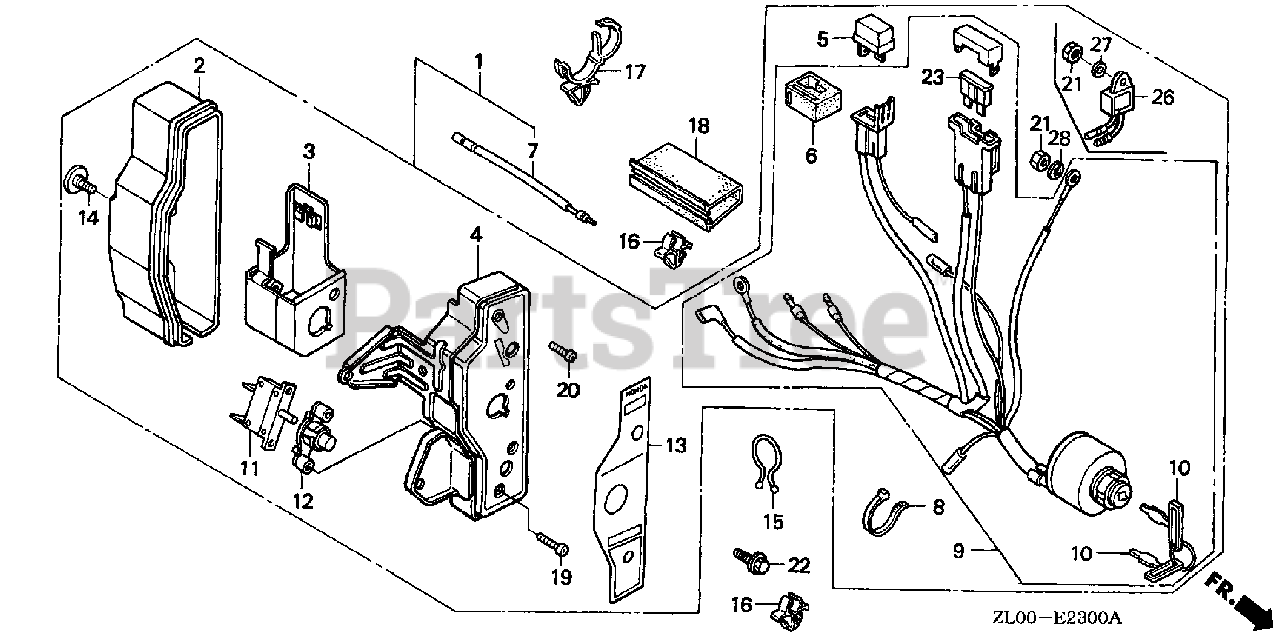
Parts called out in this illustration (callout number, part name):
1	BOX ASSY., CONTROL (EXP,10A) *R8* (BRIGHT RED)
2	CASE, CONTROL
3	BRACKET, CASE MOUNTING
4	PANEL, CONTROL *R8* (BRIGHT RED)
7	SUB-HARNESS
8	BAND
9	SWITCH ASSY., COMBINATION (10A CHG/RCM)
10	KEY
13	MARK, CONTROL BOX (EXTERNAL-REGULATOR)
14	SCREW, SPECIAL (6X12)
18	TUBE, FASTENER (30)
20	SCREW, PAN (4X12)
21	NUT, HEX. (4MM)
22	BOLT, FLANGE (6X10)
23	FUSE, BLADE (15A)
26	ALERT UNIT, OIL
27	WASHER, PLAIN (4MM)
28	WASHER, SPRING (4MM)
